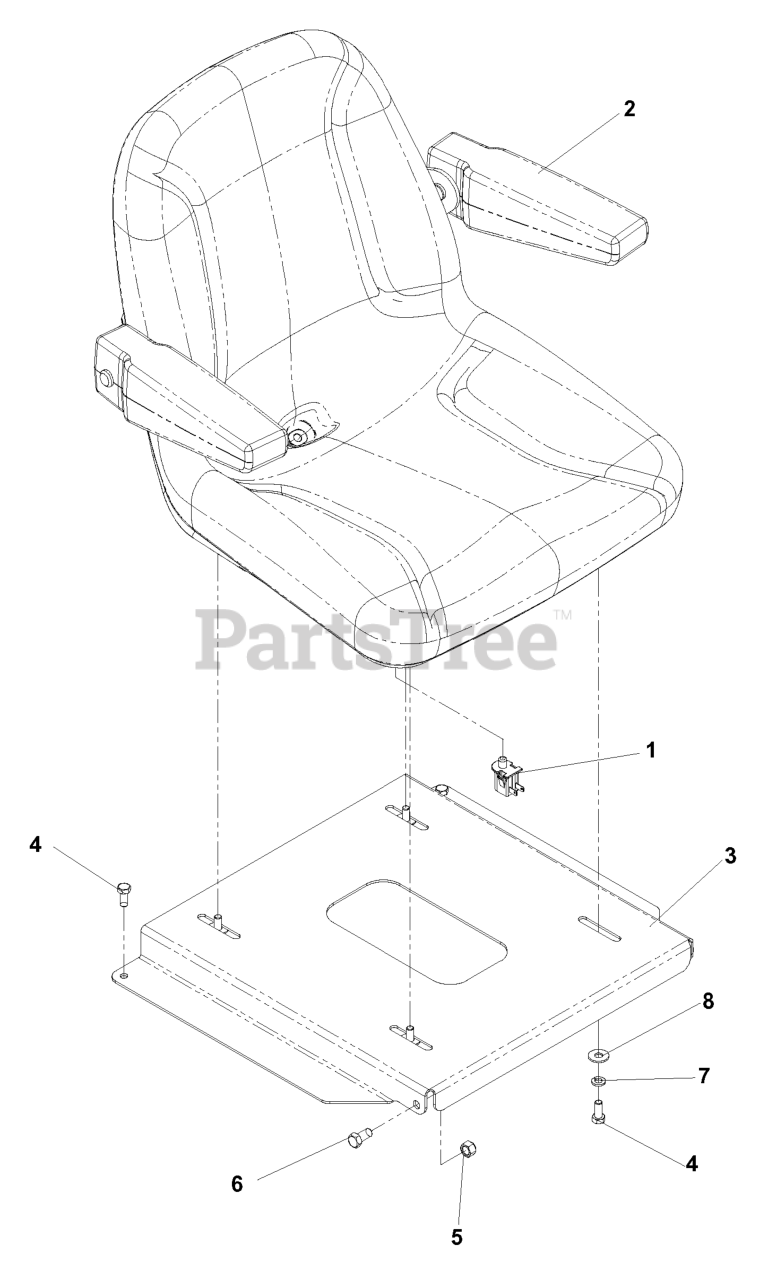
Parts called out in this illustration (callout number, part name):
1	SEAT SWITCH
2	SEAT W/ARMRESTS
3	SEAT MOUNT
4	HCS 5/16C X 3/4
5	NUT 3/8-16 NYLOC
6	SCREW 3/8C X 3/4 HEX CAP
7	WASHER.LOCK.HVY.HLCL.SPR.5/16
8	WASHER 5/16 FLAT
